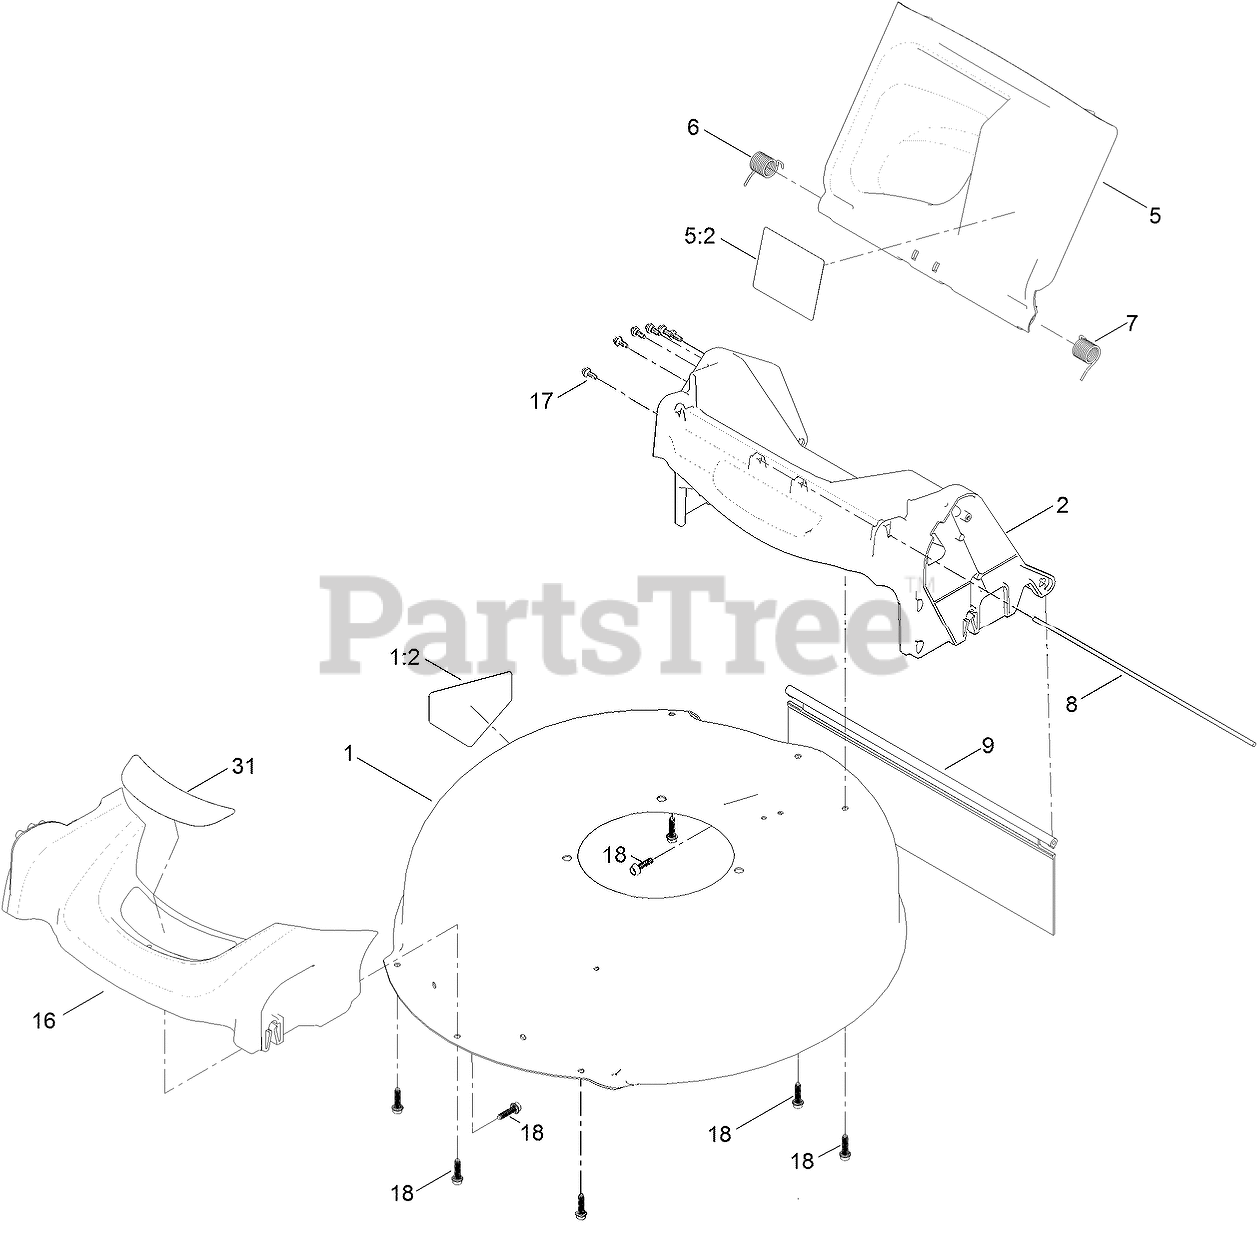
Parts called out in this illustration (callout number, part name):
1	HOUSING ASM
1:2	DECAL-DANGER
2	CHUTE ASM
5	REAR DEFLECTOR ASM
5:2	DECAL-WARNING
6	SPRING-TORSION
7	SPRING-TORSION
8	ROD-DOOR
9	SHIELD-TRAILING
16	BUMPER
18	SCREW-FLANGE, PLASTIC
31	DECAL-DECK
